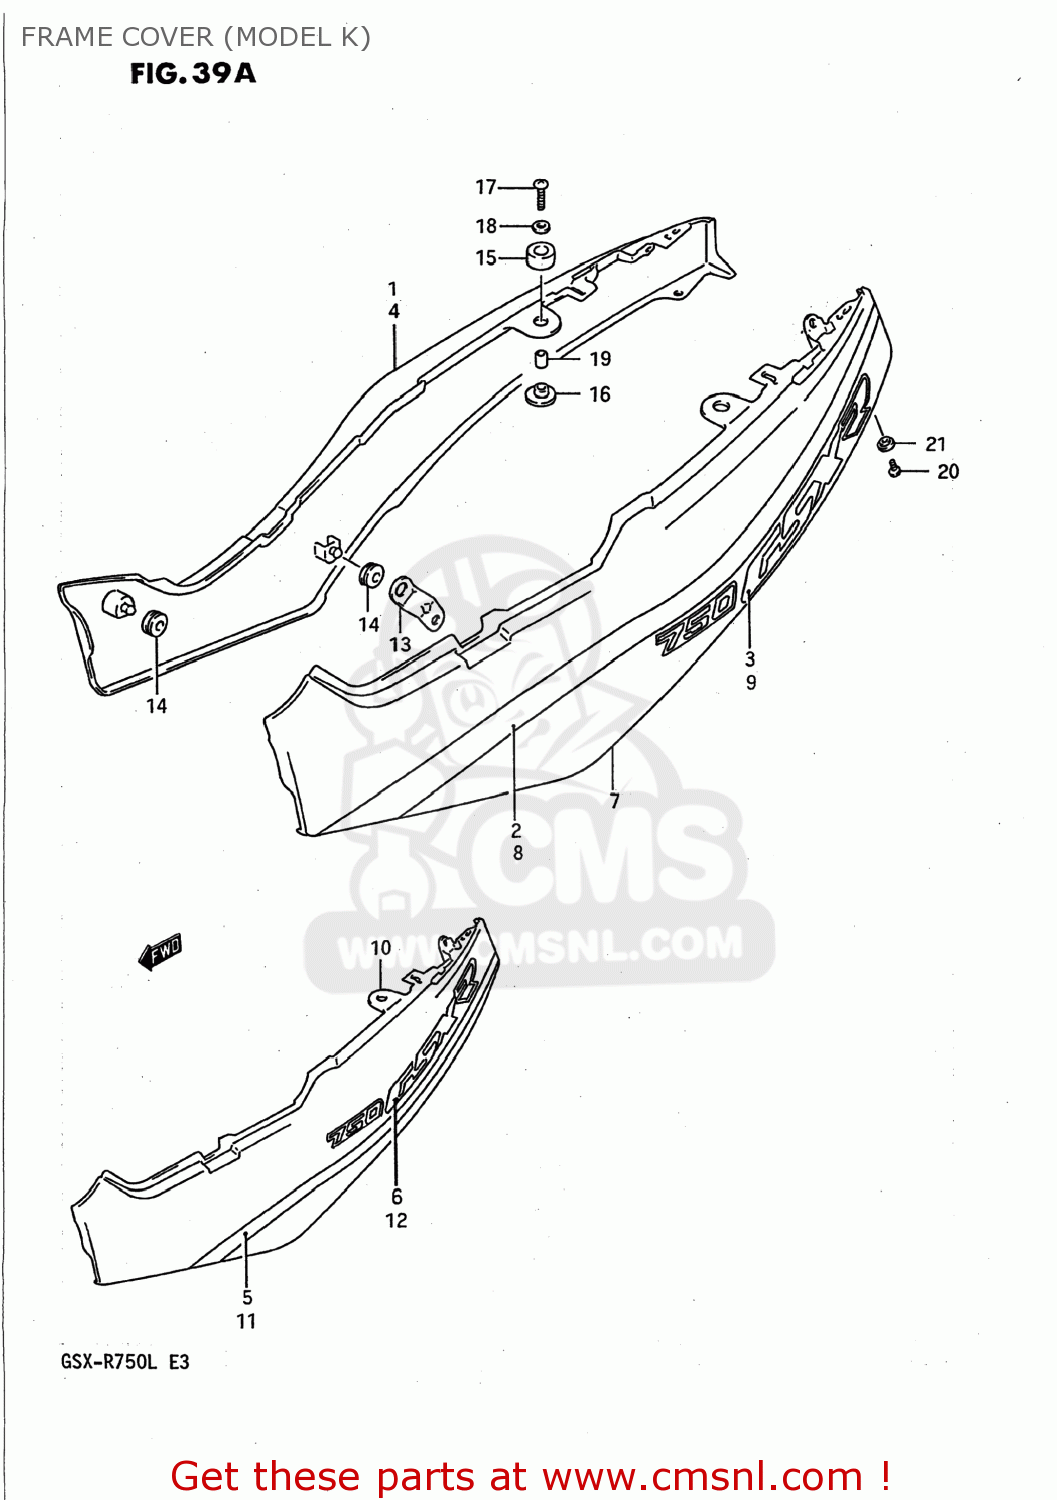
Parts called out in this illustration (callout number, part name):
1	COVER,FRAME,RIGHT
2	TAPE,FRAME COVER,RIGHT (WHITE)
3	EMBLEM,FRAME COVER,RIGHT
4	COVER,FRAME,RIGHT
5	TAPE,FRAME COVER,RIGHT (BLACK)
6	EMBLEM,FRAME COVER,RIGHT
7	COVER,FRAME,LEFT
8	TAPE,FRAME COVER,LEFT (WHITE)
9	EMBLEM,FRAME COVER,LEFT
10	COVER,FRAME,LEFT
11	TAPE,FRAME COVER,LEFT (BLACK)
12	EMBLEM,FRAME COVER,LEFT
13	BRACKET,FRAME COVER
14	CUSHION
15	CUSHION,TAIL COVER UPR
16	CUSHION,FRAME COVER LWR
17	SCREW
18	WASHER
19	SPACER
20	SCREW, FRONT & REAR
21	WASHER(5.2X14X1.5)
